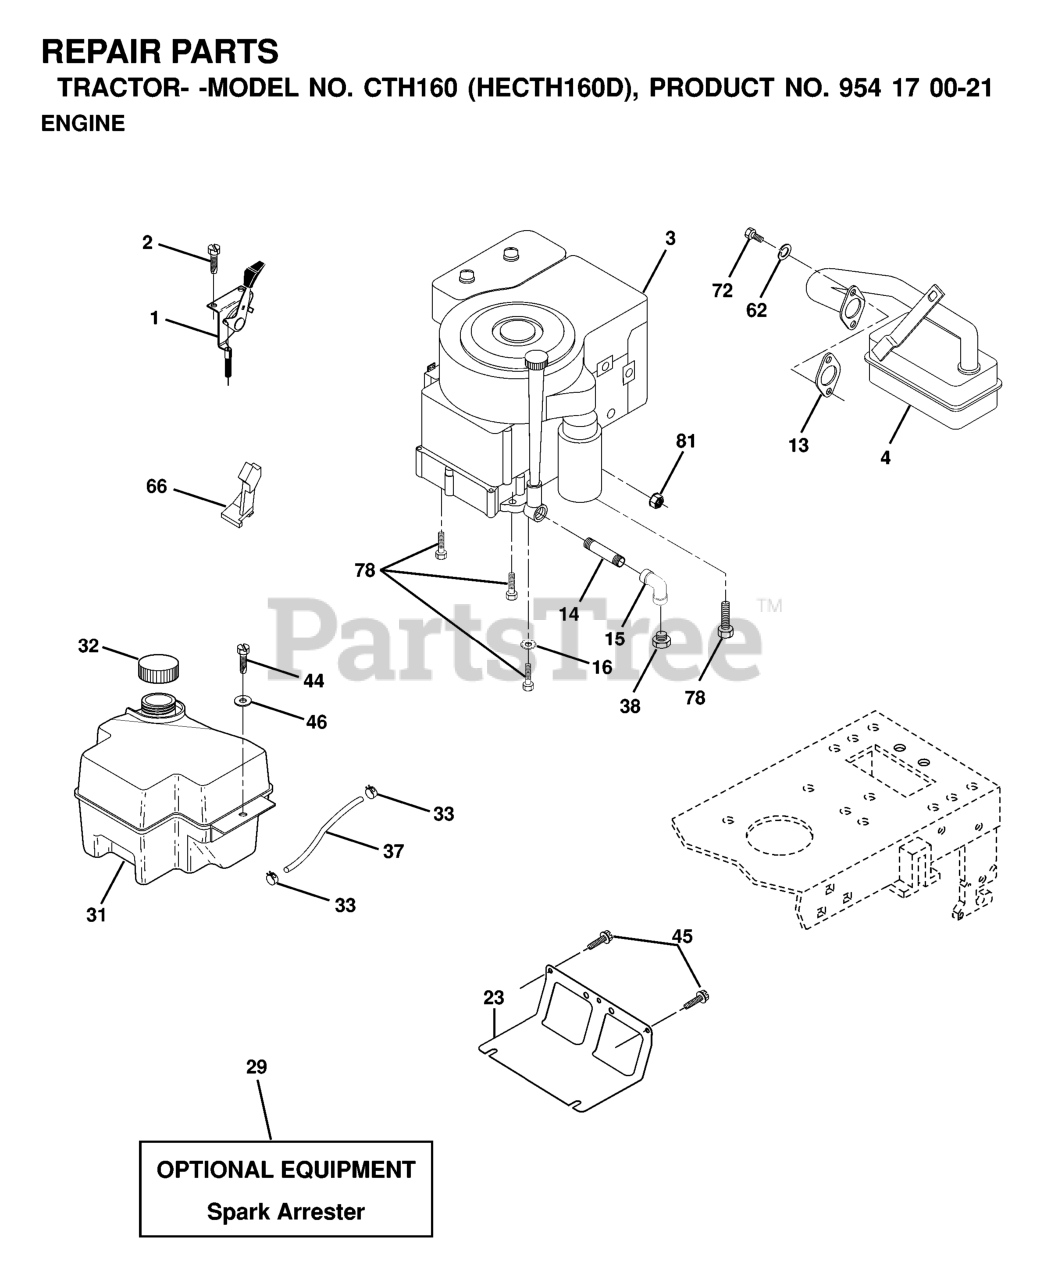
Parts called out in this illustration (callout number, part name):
1	CONTROL
2	SCREW LT
4	MUFFLER.LT.BRIGGS.14HP.IC/OHV
13	REPL BY 532 27 22-93
14	Nipple Pipe 3/8 Npt X 3-1/2
15	ELBOW
16	LOCKWASHER
23	SHIELD.BROWNING.DBR.GUARD
29	KIT.SPARK ARRESTOR 794945 B&S
31	FUEL TANK
32	FUEL CAP
33	HOSE CLAMP
37	LINE.FUEL.20
45	SCREW 3/8-16X3/4
62	WASHER.LOCK.HVY.HLCL.SPR.5/16
66	STOP THROTTLE
72	SCREW
78	SCREW.3/8-16
81	NUT FLANGE 1/4-20 STARTER NUT
